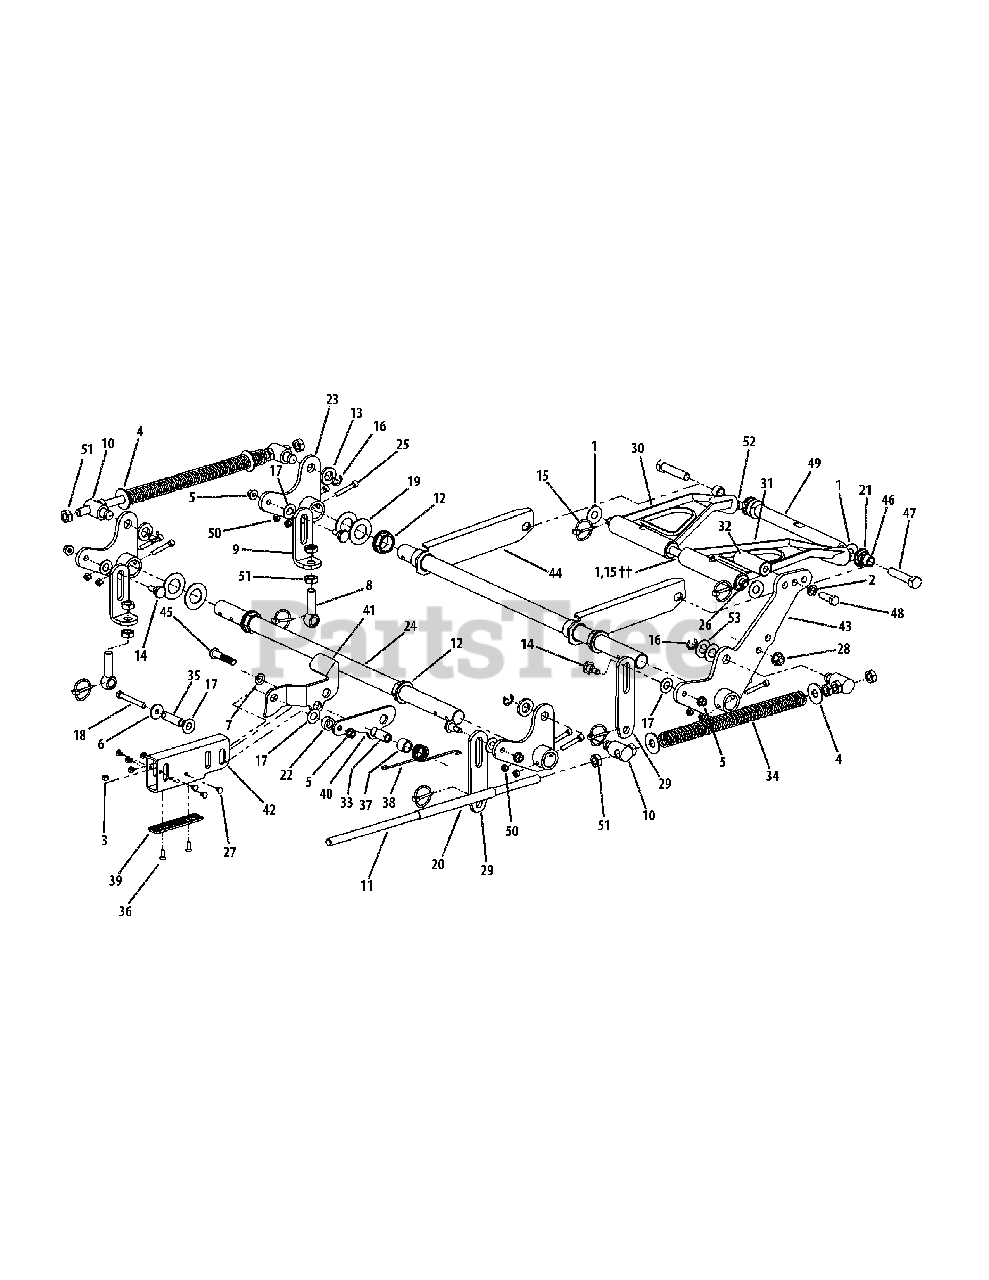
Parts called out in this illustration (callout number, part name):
1	Washer, 1.5 x .655 x .055
2	Lock Washer, 1/2
3	Lock Nut w/Nylon Insert
4	Flat Washer, 5/8
5	Hex Nut, Flange Lock, 3/8-16
6	Flat Washer, 1.25 x .411 x .100
7	Flat Washer, .536 ID x .930 OD x .05
8	Eye Bolt, 5/8ID
9	Eye Bolt Mount Link, 5/8 ID
10	Ferule Lift
11	Lift Connector Rod
12	Hex Flange Bearing, 1.25 ID
13	Spacer, .812 ID x .268 Lg.
14	Shoulder Screw, 0.625 OD x .437 Lg.
15	Linch Pin, 3/16 Dia.
16	Clip, 3/4 Dia.
17	Nylon Flat Washer, 5/8
18	HHCS, 3/8-16, 3.00
19	Flat Washer, 1.25 ID
20	Hose, 5/8 ID 13/16 OD, 8" LG
21	Rod End, Male
22	Spacer, .630 ID x 1.06 OD x .440
23	Bellecrank Assembly
24	Deck Lift Shaft
25	Socket Head Cap Screw, 5/16-18
26	Lift Link Rod 54"/60"
26	Lift Link Rod 72"
27	Rivet, 1/4 x 5/8
28	Nut, 1/2-13, Flange Lock
30	Bearing Lift Brace Ass’y, LH
30	Grease Fitting
31	Bearing Lift Brace Ass’y, RH
31	Grease Fitting
32	Deck Lift Foot Pedal
33	Spacer, .51 ID x .75 OD x 1.240
34	Lift Compression Spring 54"
34	Lift Compression Spring 60"/72"
35	Spacer, .375 ID x .625 OD x 2.20
36	Flat Head Cap Screw, 1/4-20 x .75
37	Spacer, .76 ID x 1.0 OD x .75
38	Torsion Spring, .120 Wire x 1.32 OD
39	Lift Wear Plate
41	Lift Link Bracket
42	Lift Tube, 3.0 x 1.5
43	Deck Lift Foot Pedal Weldment
44	Front Frame Strut Ass’y 54"/60"
44	Front Frame Strut Assembly 72"
45	Cap Screw, 1/2-13 x 2.50
46	Spacer, .632 x .877 x .548
47	HHCS, 5/8-11 x 3.00
48	Hex Cap Screw, 1/2-13 x 1.50
49	Front Lift Link Shaft, Threaded
50	Nut, 5/16-18, Nylock
51	Jam Nut, 5/8-11
52	Jam Nut, 5/8-18
53	Flat Washer, .76 x 1.49 x .06
